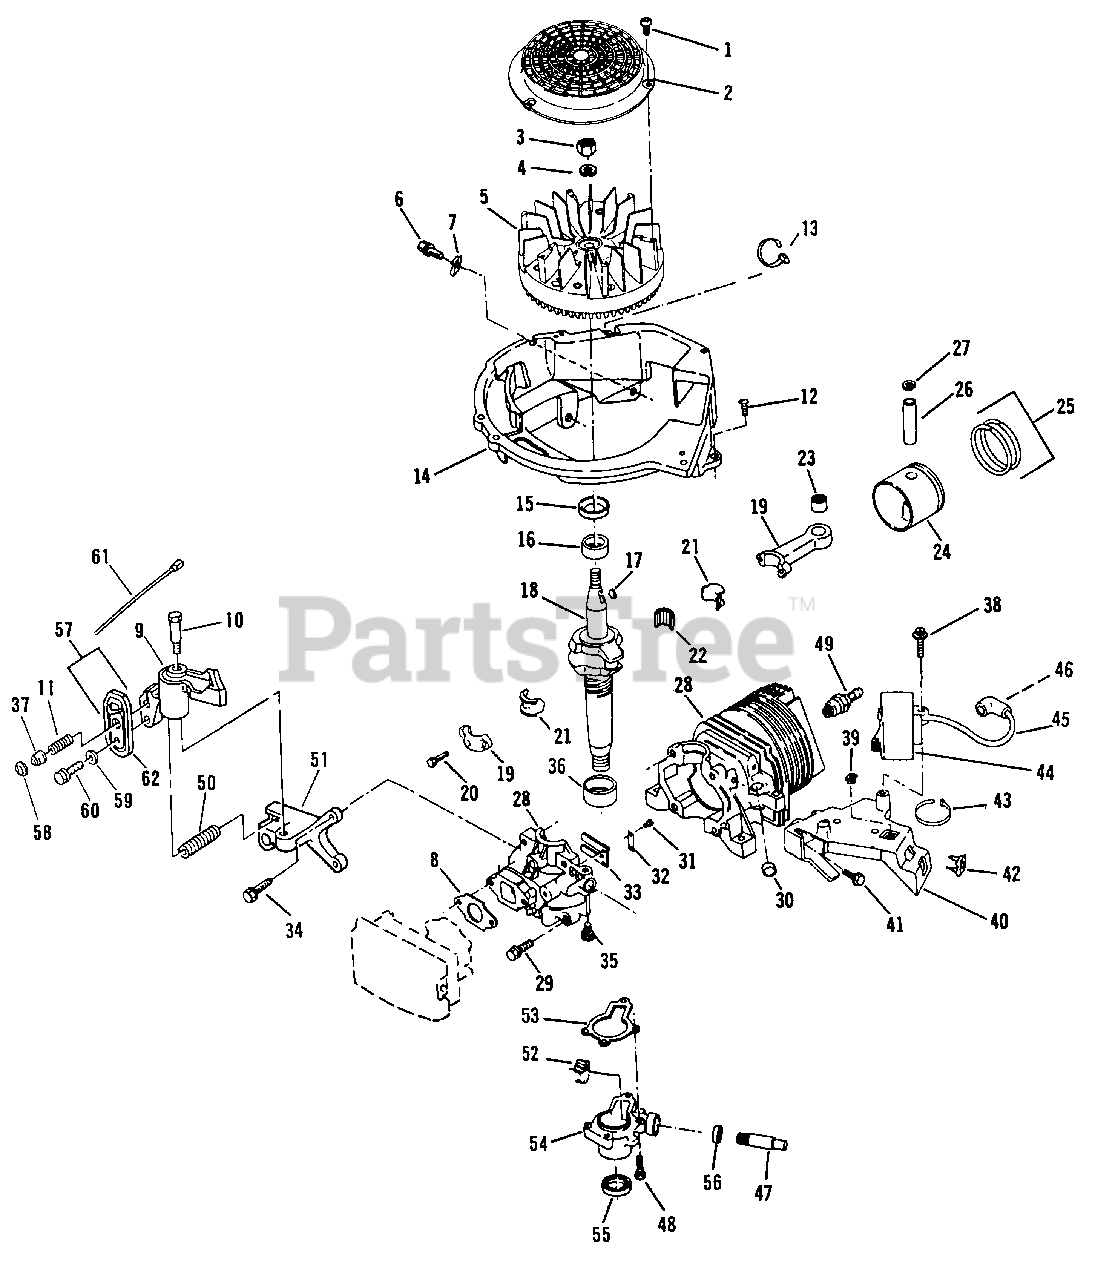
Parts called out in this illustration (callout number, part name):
1	Screw-Flywheel
2	Screen-Flywheel
3	Nut-Flywheel
4	Lockwasher
5	Flywheel
6	Screw
7	"J" Clip
8	Gasket-Carb. to Crankcase Cvr.
9	Brake Assembly
10	Bolt-Shoulder
11	Spring-Cable Retainer
12	Screw-Shroud Base to C.D. Brkt.
13	Tie Strap
14	Base-Shroud
15	Oil Seal-Upper
16	Bearing-Upper
17	Key-Flywheel
18	Crankshaft
19	Connecting Rod Assembly
20	Screw-Cap
21	Liner Split
22	Needle Bearing Set
23	Bearing Assembly
24	Piston and Ring Set
25	Ring Set
26	Wrist Pin
27	Retaining Ring
28	Cylinder and Crk'c Cover Asy
29	Screw-Cover to Crankcase
30	Plug
31	Screw-Reed to Crk'c Cover
32	Plate-Reed Hold Down
33	Reed
34	Screw-Brake Mtg. Brkt.
35	Set Screw-Starter Assembly
36	Bearing-Lower
37	Actuator-Brake Lever
38	Screw-C.D. Mounting
39	Grommet-C.D. Bracket
40	Bracket-Ignition Mounting
41	Screw
42	Grommet-C.D. Bracket
43	Tie Strap
44	C.D. Ignition Module and Lead Asy
45	High Tension Lead and Cvr. Asy
46	Spring Terminal
47	Driveshaft
48	Screw-Gear Box
49	Spark Plug
50	Spring-Brake
51	Bracket-Brake
52	Gear
53	Gasket-Gear Box
54	Gear Box Assembly
55	Oil Seal Crankshaft
56	Seal-Driveshaft
57	Switch Assembly
58	Retainer
59	Washer
60	Screw
61	Lead Assembly
62	Case Assembly Only
